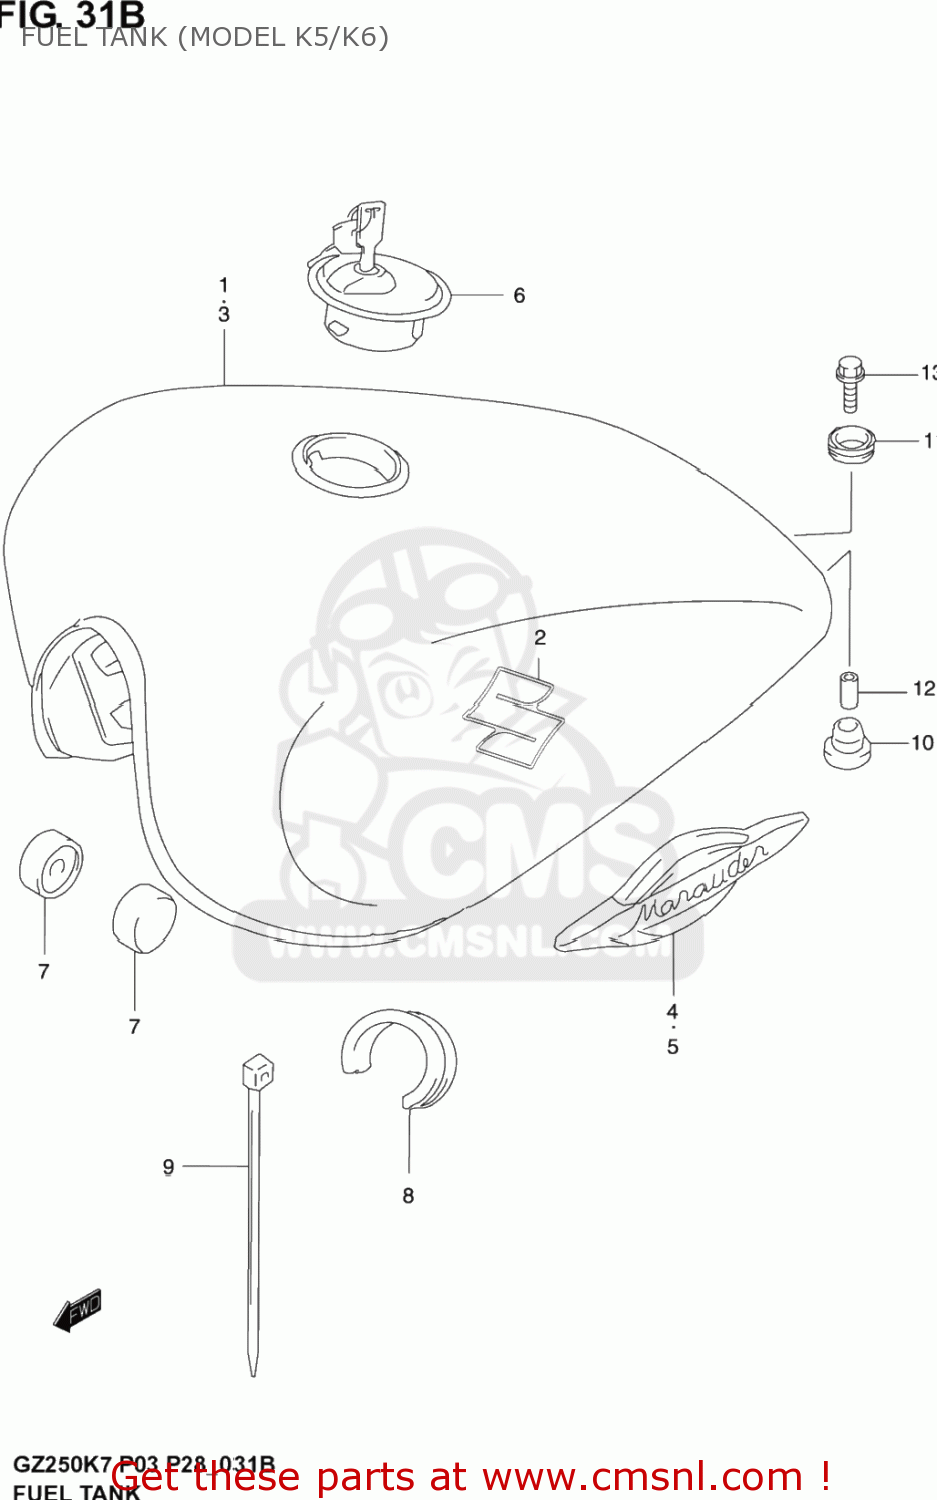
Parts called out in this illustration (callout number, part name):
1	TANK ASSY,FUEL(BLACK)
2	EMBLEM,S
3	TANK ASSY,FUEL(BLUE)
6	CAP SET,FUEL TANK
7	CUSHION
8	CUSHION,FUEL TANK SIDE
9	CLAMP
10	CUSHION
11	CUSHION,FUEL TANK RR
12	SPACER(6.5X9X18)
13	BOLT
